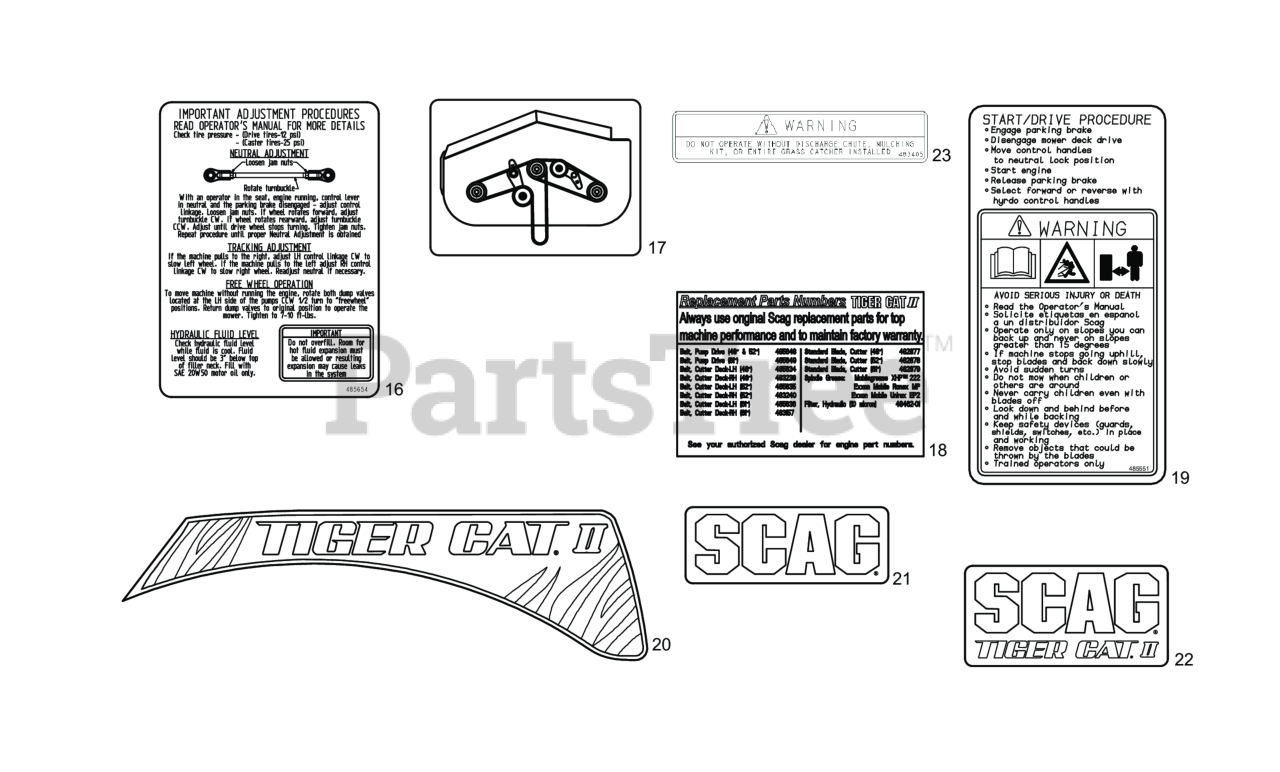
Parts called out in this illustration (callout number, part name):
16	Decal, Seat Support
17	Decal, Cutter Deck Belt Routing
18	Decal, STCII Replacement Parts
19	Decal, Start/Drive
20	Decal, Tiger Cat II - LH
20	Decal, Tiger Cat II - RH
21	Decal, Scag
22	Decal, Scag Tiger Cat II
23	Decal, Warning-Discharge
